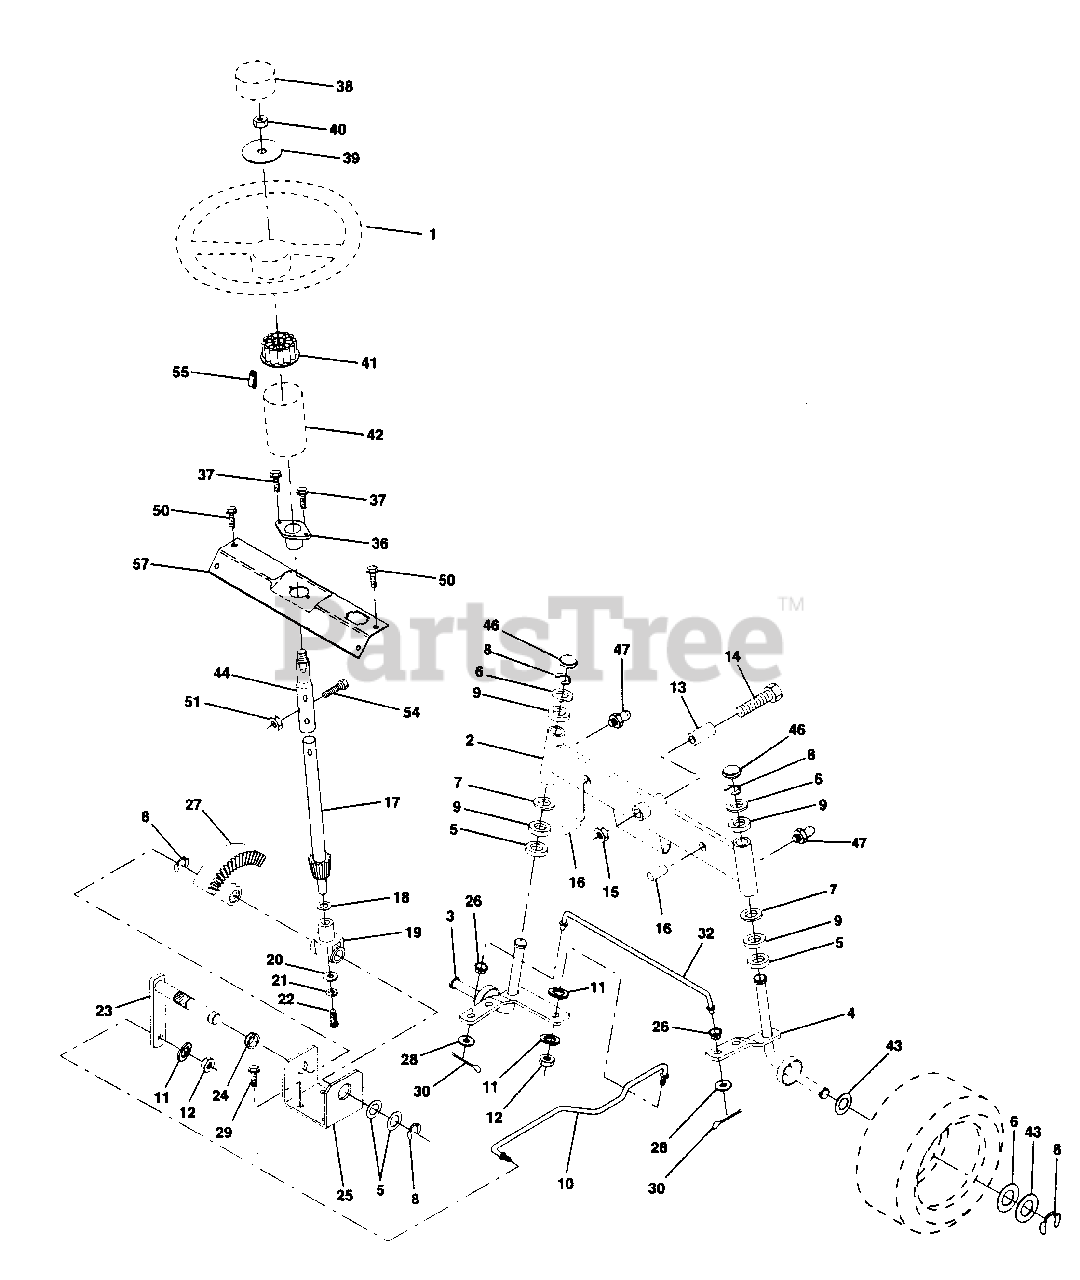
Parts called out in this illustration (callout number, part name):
1	Wheel Steering Auto Blk (AYP part number)
2	Axle Asm Fr LT W/gzks 38/42 (AYP part number)
3	Spindle Asm LH (AYP part number)
4	Spindle Asm RH
5	Bearing Race Thrust Harden (AYP part number)
6	Washer 25/32 X 1-5/8 X 16 Ga (AYP part number)
7	Washer 27/32 X 1-1/4 X 16 Ga (AYP part number)
8	Ring Klip #t5304-75 (AYP part number)
9	Bearing Col Strg Blk (AYP part number)
10	Link Drag Sol Ball Jt 20 064 (AYP part number)
11	Washer Lock Hvy Hlcl Spr 3/8 (AYP part number)
12	Nut Fin Hex 3/8-24 Unf (AYP part number)
13	Spacer Bearing Axle Front (AYP part number)
14	Bolt Hex 5/8-11 Unc X 3-1/2 (AYP part number)
15	Nut Lock Flange 5/8-11 Unc (AYP part number)
16	Pin Axle 5/8 X 1 55/1 54 Lg (AYP part number)
17	Shaft Asm Strg Private Label (AYP part number)
18	Washer Thrust 515x 750x 033 (AYP part number)
19	Support Shaft (AYP part number)
20	Washer Shim 1/4 X 5/8 X 062 (AYP part number)
21	Washer Lock Hvy Helical 1/4 (AYP part number)
22	Screw Hex Socket 1/4-20 X 5/8 (AYP part number)
23	Shaft Asm Pittman (AYP part number)
24	Nyliner Snap In (AYP part number)
25	Bracket Steering (AYP part number)
26	Bushing Link Drag Blk LR (AYP part number)
27	Gear Sector (AYP part number)
28	Washer 13/32 X 7/8 X 16 Ga (AYP part number)
29	Screw Thdrol 3/8-16x3/4 Ty-tt (AYP part number)
30	Pin Cotter 1/8 X 3/4 Cad (AYP part number)
32	Rod Tie Wire Form 19 75 Mech (AYP part number)
36	Bushing Strg (AYP part number)
37	Screw Slftp #10-16 X 1/2 Ty-b (AYP part number)
38	Insert Cap Strg Wh Au (AYP part number)
39	Washer 13/32 X 2-3/8 X 8 Ga (AYP part number)
40	Nut Lock Center 3/8-24unf (AYP part number)
41	Adaptor Wheel Strg 640/ 635id (AYP part number)
42	Boot Steering Shaft (AYP part number)
43	Washer 25/32 X 1 1/4 X 16 Ga (AYP part number)
44	Shaft Extention Steering (AYP part number)
46	Cap Spindle Fr Top Blk (AYP part number)
47	Fitting Grease (AYP part number)
50	Screw Hex Wsh Thdrol 1/4-20 x 3/4 (AYP part number)
51	Nut Lock Hex w/Ins 5/16-18 (AYP part number)
54	Bolt Fin Hex 5/16-18 Unc x 1-1/4 (AYP part number)
55	Clip Tinnerman (AYP part number)
57	Support Shaft Steering (AYP part number)
